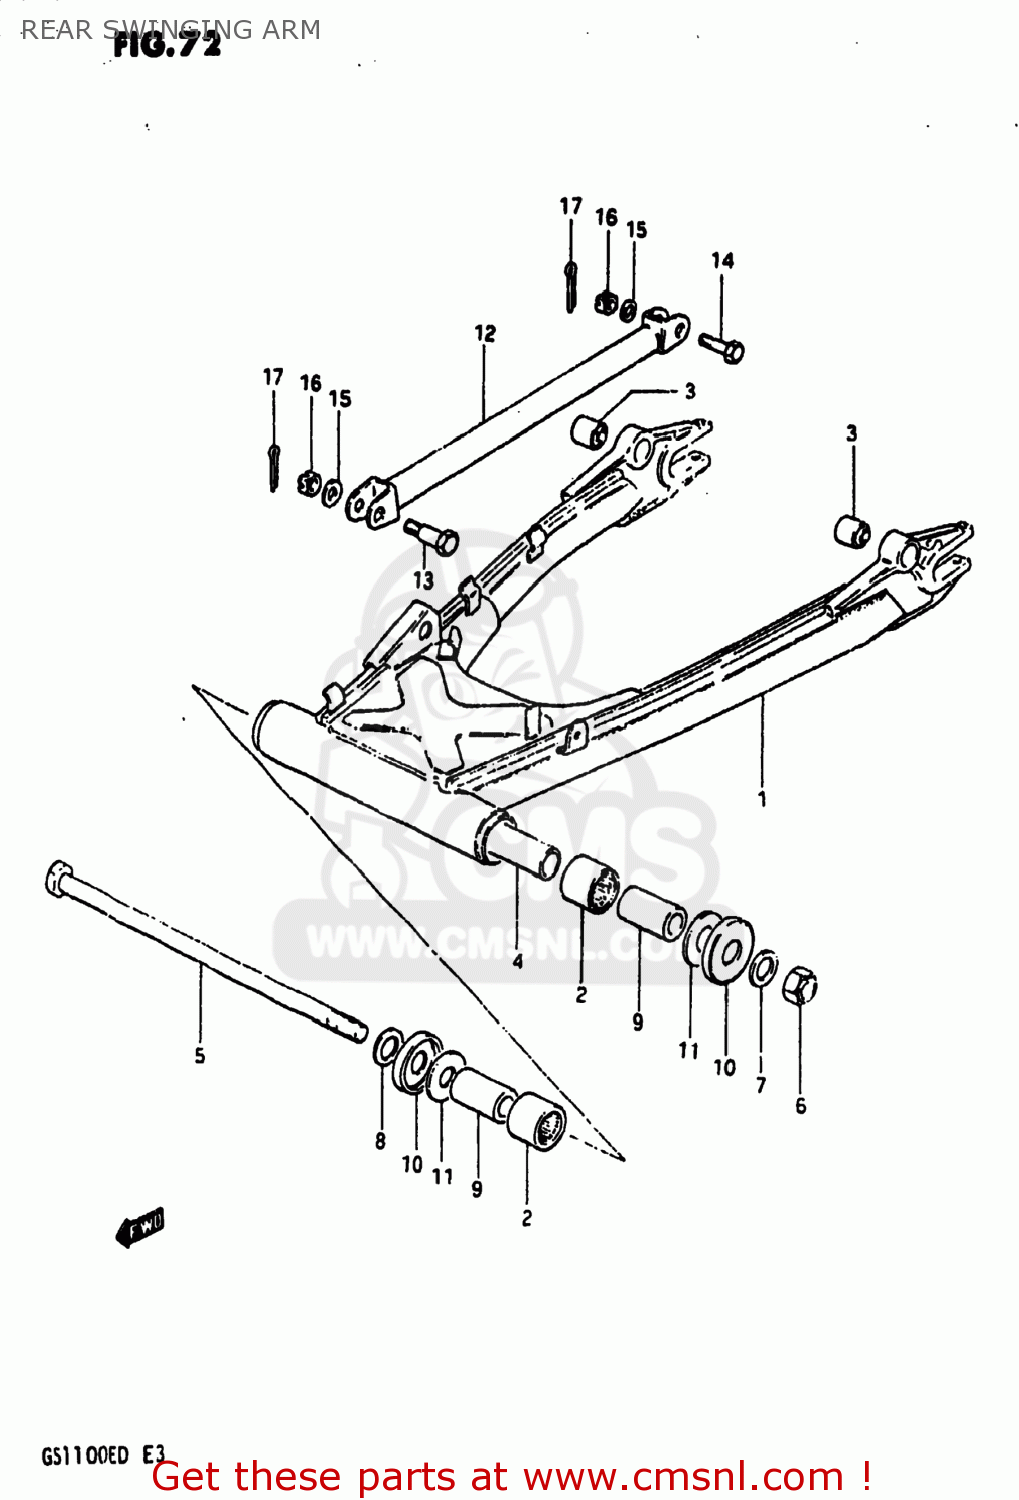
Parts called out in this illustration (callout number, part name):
1	SWING ARM ASSEMBLY,REAR
2	BEARING(25X33X30)
3	BUSH
4	SPACER,RR SWGARM PIVOT CTR
5	SHAFT,REAR SWING ARM
6	NUT 16MM
7	WASHER
8	WASHER
9	SPACER,RR SWGARM PIVOT
10	COVER,RR SWINGINGARM PIVOT
11	WASHER
12	LINK,RR TORQUE
13	BOLT
14	BOLT(10X39)
15	WASHER
16	NUT
17	PIN 20X20
